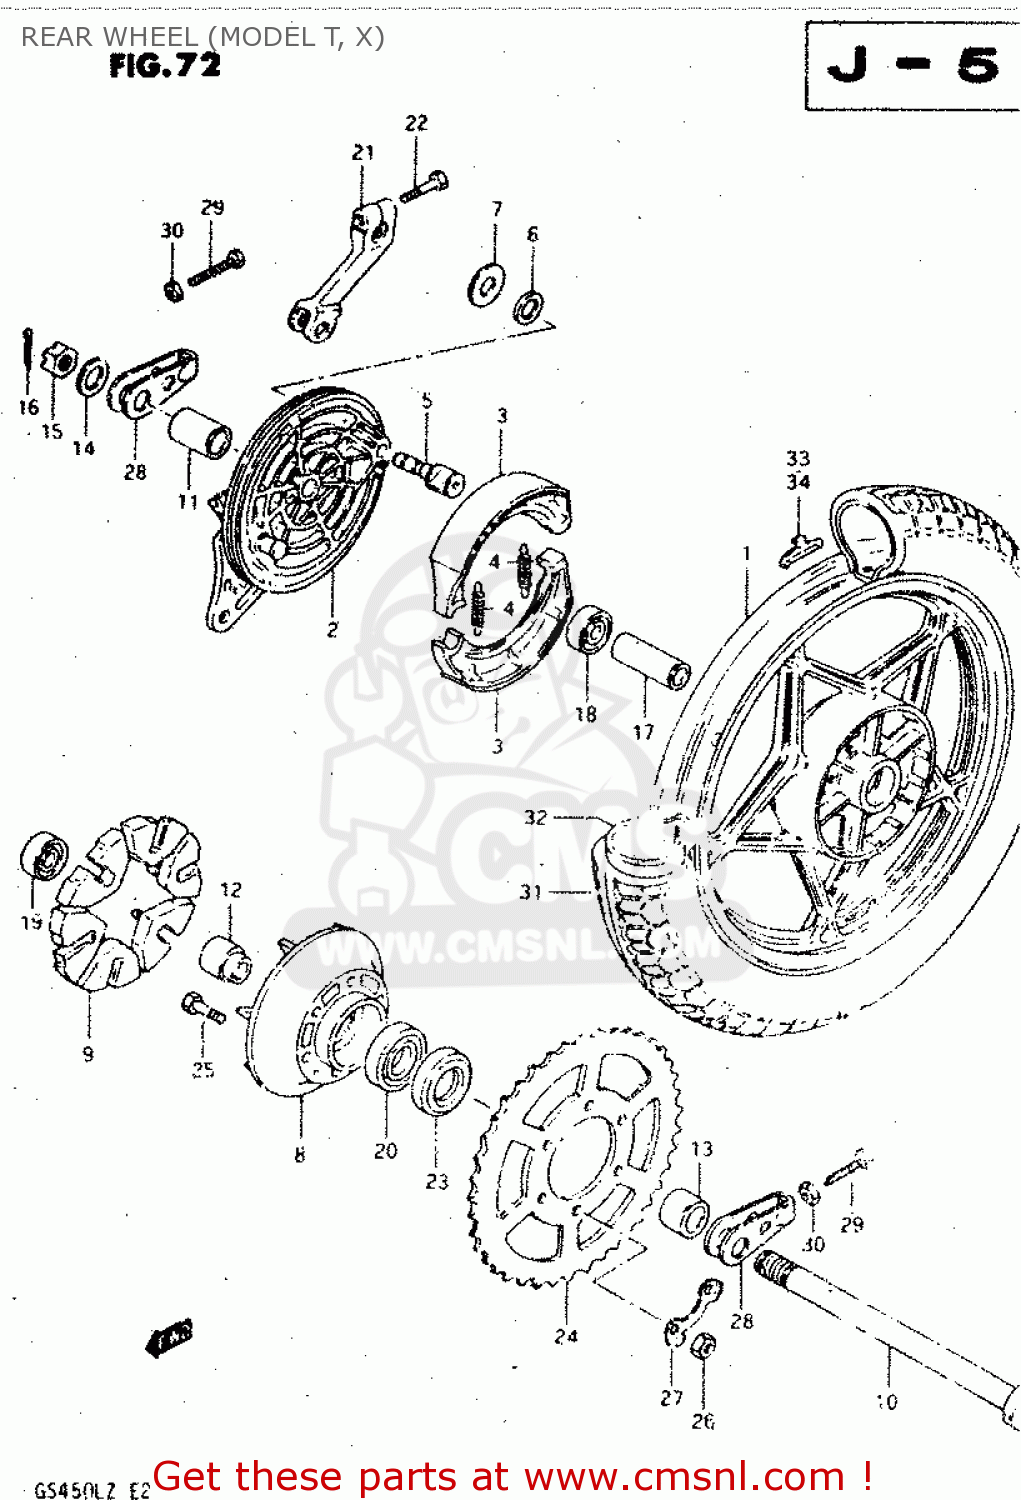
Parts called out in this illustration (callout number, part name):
1	WHEEL,REAR
2	PANEL,REAR HUB
3	SHOE,BRAKE
4	SPRING,BRAKE SHOE
5	CAM,FRONT BRAKE
6	O-RING,BOSS
7	WASHER (15X24X1.6)
8	DRUM,REAR SPROCKET MOUNT
9	ABSORBER,RR HUB SHOCK
10	AXLE,REAR
11	SPACER(17.5X28X44.8)
12	SPACER,REAR HUB BEARING
13	SPACER(17X30.5X22.3)
14	WASHER (17X30X3.2)
15	NUT
16	PIN,COTTER
17	SPACER (17.6X24X57)
18	BEARING
19	BEARING
20	BEARING
21	LEVER,RR BRAKE CAM
22	BOLT
23	SEAL,OIL(30.5X52X8)
24	SPROCKET,REAR (NT:41)
25	BOLT
26	NUT
27	WASHER
28	ADJUSTER,CHAIN
29	BOLT 8X50
30	NUT
31	TIRE
32	TUBE ASSY,WHEEL,INNER 4.60-16
33	BALANCER,WHEEL
34	BALANCER,WHEEL
